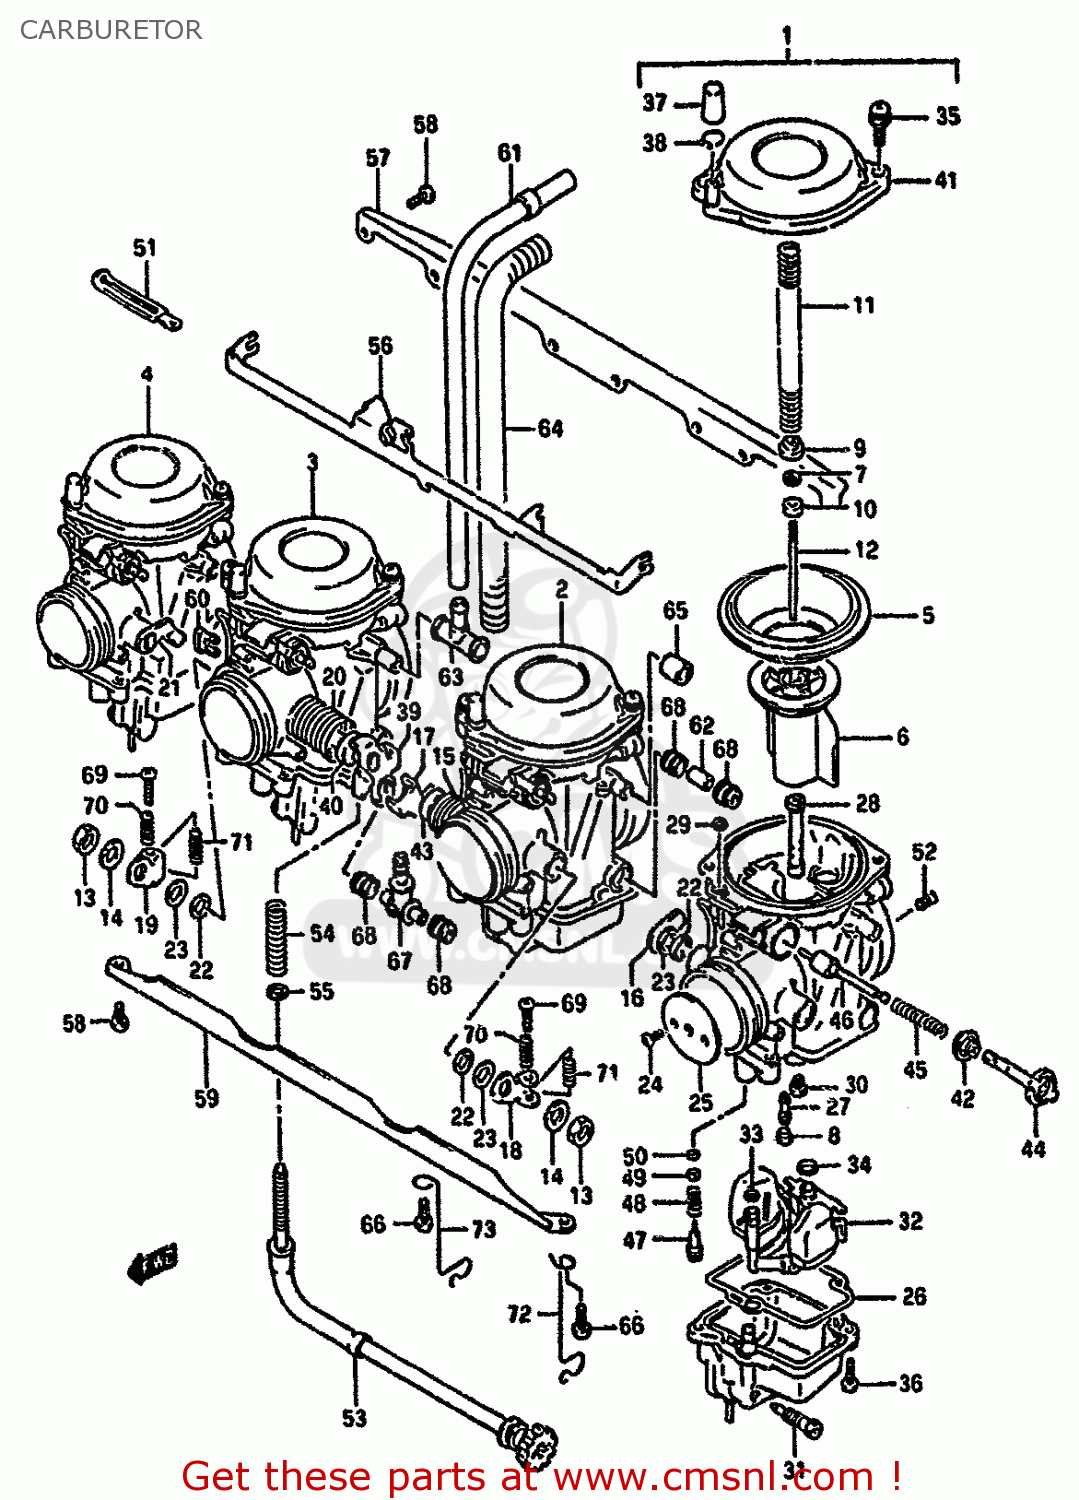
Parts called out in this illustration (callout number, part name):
1	CARBURETOR ASSY,LH
2	CARBURETOR,ML.
3	CARBURETOR,MR
4	CARBURETOR,RH.
5	DIAPHRAGM
6	VALVE,PISTON
7	CLIP
8	9
9	10
10	RING
11	SPRING
12	NEEDLE,JET
13	14
14	WASHER,LOCK,8.
15	SPRING
16	SHAFT ASSY
17	SHAFT ASSY
18	LEVER
19	LEVER,THROTTLE
20	SPRING
21	SHAFT ASSY
22	SEAL
23	GASKET,THROTTLE SHAFT (NAS)
24	SCREW
25	VALVE,THROTTLE (130)
26	27
27	JET,PILOT(32.5)
28	JET,NEEDLE(O-9)
29	30-1
30	JET,MAIN(102.5)
31	SCREW,DRAIN
32	FLOAT/NEEDLE VALVE ASSY
33	O RING
34	35
35	SCREW
36	37
37	CAP
38	CLIP
39	SHAFT ASSY
40	RING
41	COVER,DIAPHRAGM
42	CAP,STARTER
43	RING
44	HOLDER,GUIDE
45	SPRING
46	PLUNGER ASSY
47	SCREW,PILOT
48	SPRING
49	50
50	51-1
51	51-2
52	JET,AIR
53	ADJUSTER ASSEMBLY
54	SPRING
55	WASHER
56	LEVER
57	PLATE
58	59
59	PLATE
60	HOLDER
61	HOSE
62	PIPE
63	3 WAY
64	PROTECTOR,HOSE
65	HOSE
66	SCREW
67	NIPPLE
68	SEAL
69	SCREW
70	SPRING
71	SPRING
72	CLIP
73	CLIP
